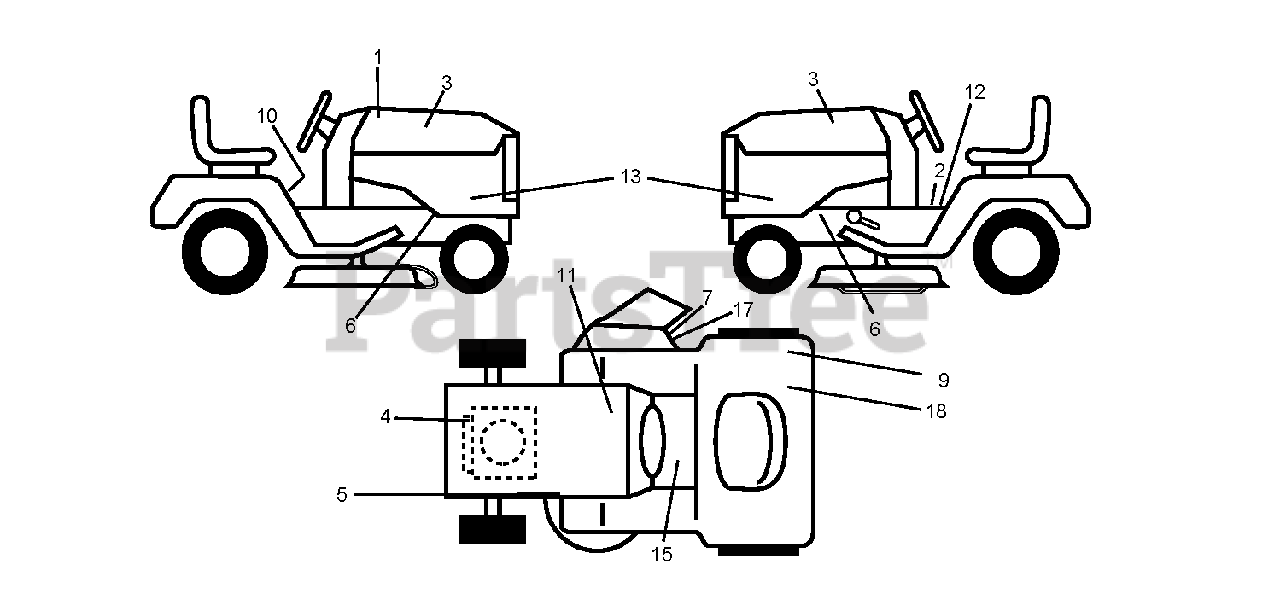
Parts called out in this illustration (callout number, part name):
1	DECAL
2	DECAL PARK BRAKE
3	RP.DECAL.BADGE.170MM.TEXTLOGO
4	DECAL
5	DECAL V BELT SCHEMATIC
7	DECAL.INTERNATIONL.CUTFINGER
9	DECAL
10	LABEL
11	DECAL BTRY SYMBOLS
12	DECAL
13	DECAL.SDPNL.LTH1842.KOH.HUSQ
15	DECAL
17	DECAL, DEFLECT WARNING
18	DECAL 80 DBA
